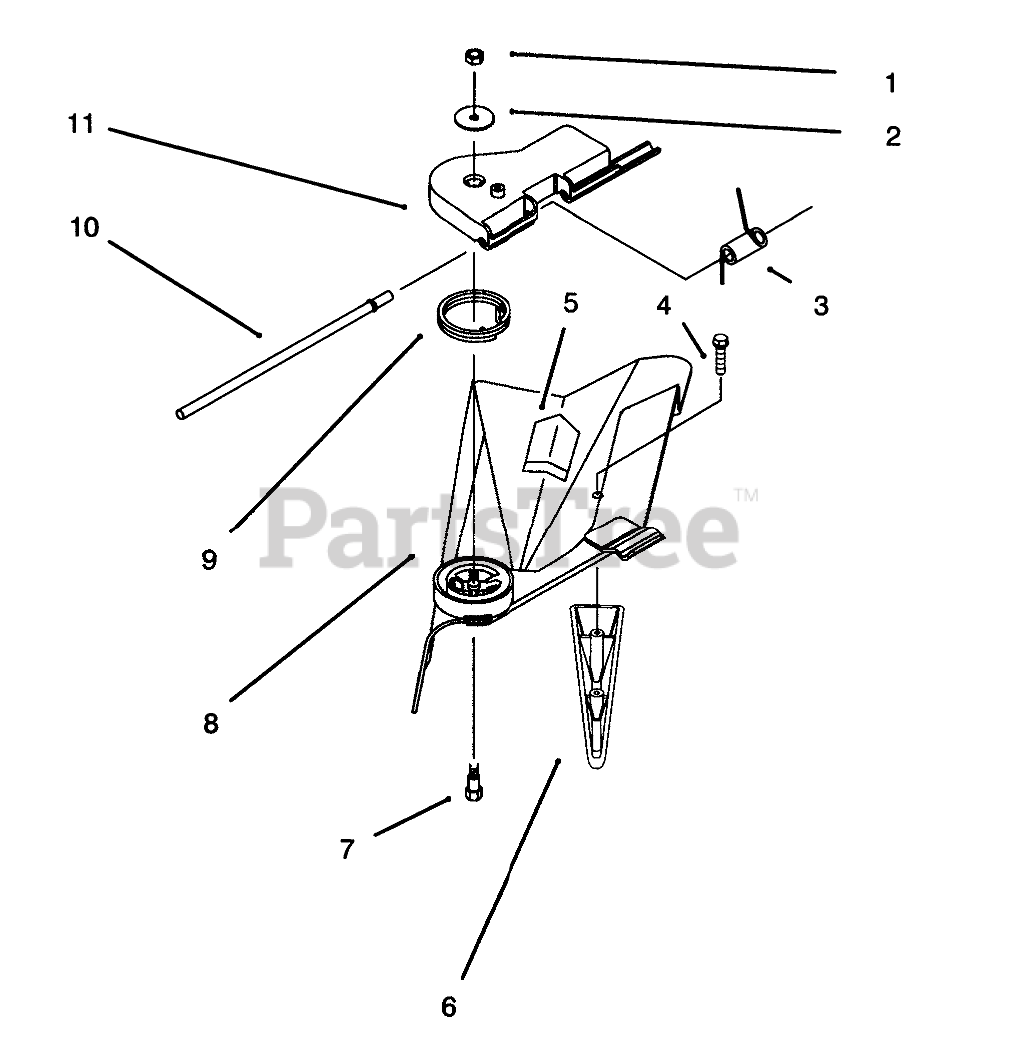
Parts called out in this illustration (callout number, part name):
1	NUT-LOCK, NI
2	WASHER-FLAT
3	SPRING-TORSION
4	SCREW-PPH
5	DECAL-DANGER
6	KICKER
7	BOLT-SHOULDER
8	Deflector Assembly (Incl. Ref. #4-6)
9	SPRING-TORSION
10	ROD-HINGE, DEFLECTOR
11	PIVOT-HINGE, DEFLECTOR
